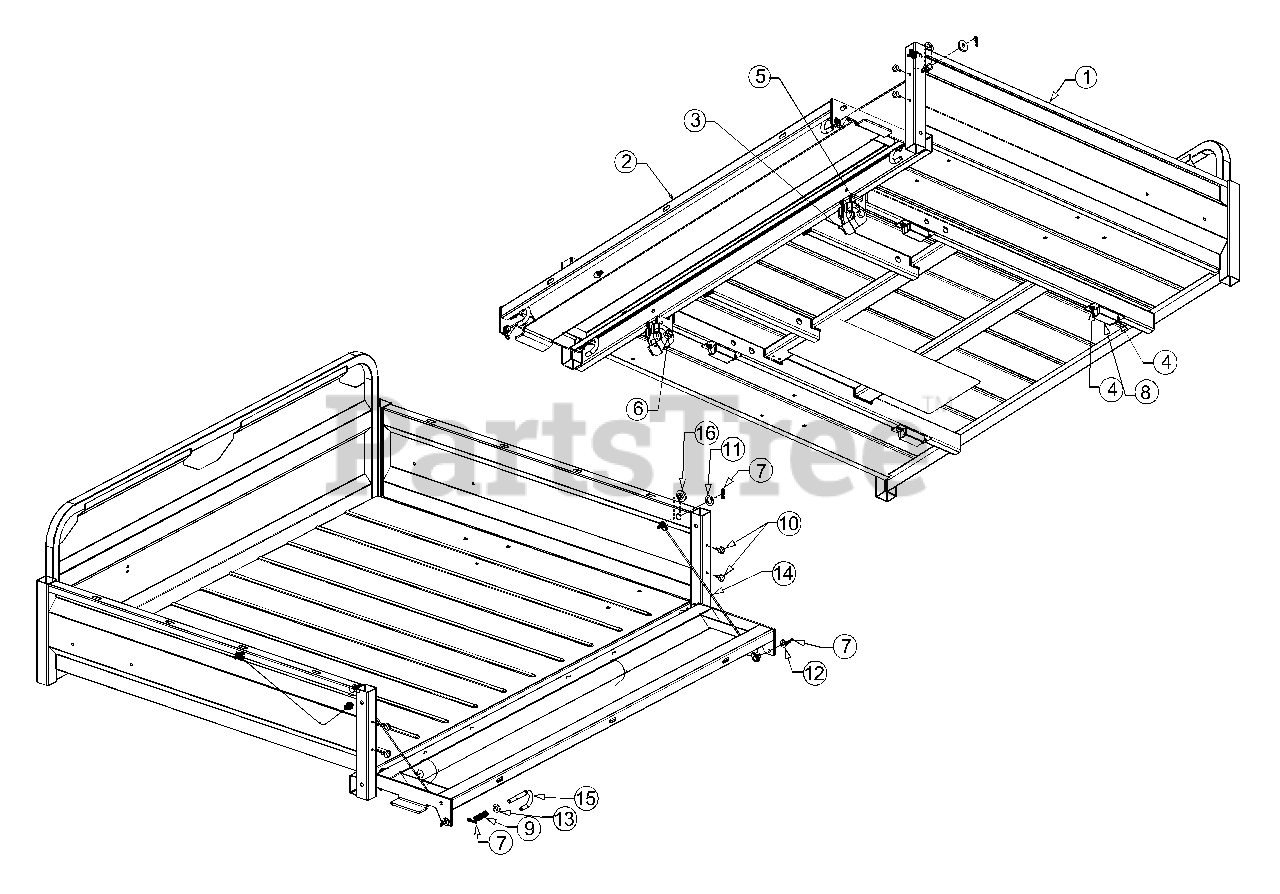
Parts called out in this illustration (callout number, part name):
1	Bed Assembly, Utility
2	Tailgate Assembly
5	Screw, Hex 1/2-13 x 2.50 GR5
6	Nut, Hex Lock, 1/2-13
7	Cotter Pin, .072 Dia x 1.13LG
8	Bumper, Extension Suspension
9	Compression Spring, .406 x .531 x 1.75 LG
10	Bumper, .62Dia x .3
11	Washer, Flat, .64 ID x 1.0 x .12
12	Washer, Flat, .344 x .750 x .120
13	Washer, Flat, .407 x .812 x .135 HDN
14	Cable, LIft 16.16 LG
15	Handle, Deck Release
16	Spacer, Shoulder .625 Dia x .324 Dia
